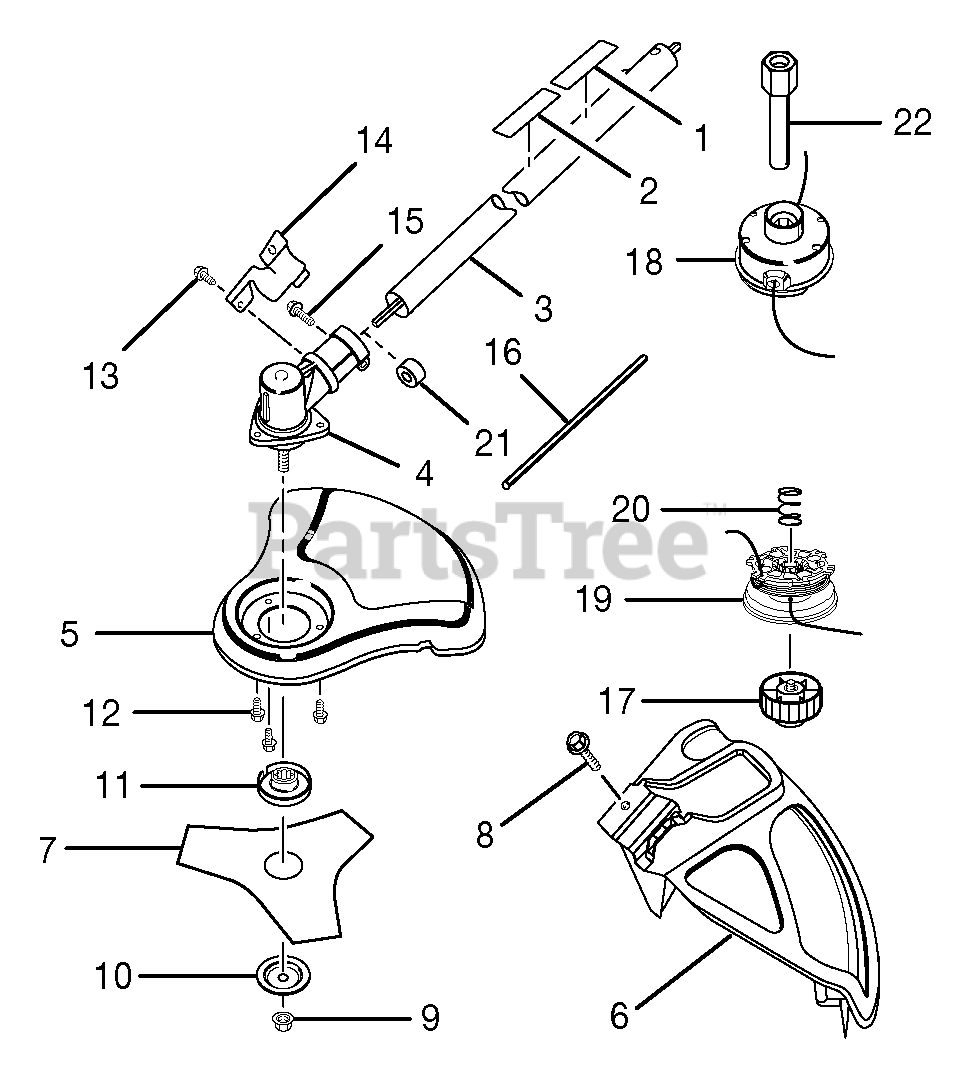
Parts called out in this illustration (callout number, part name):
1	Expand-it Label
2	Warning Decal
3	Brushcutter Assy.
4	Gear Case Assembly
5	8 in. Blade Guard
6	Grass Deflector Assy.
7	Tri-Arc(R) Blade
8	Screw (1/4-20 x 0.70-0.75 in.)
9	Lock Nut
10	Cupped Washer
11	Flanged Washer
12	Screw (10-24 x 1/2 in.)
13	Screw (10-24 x 5/8 in.)
14	Clamp
15	Screw (1/4-20 x 1-1/4 in.)
16	Holding Pin
17	Spool Retainer (Red)
18	Complete String Head (.095 in.)
19	Spool and String (.095 in.)
20	Compression Spring
22	Shaft Adapter
